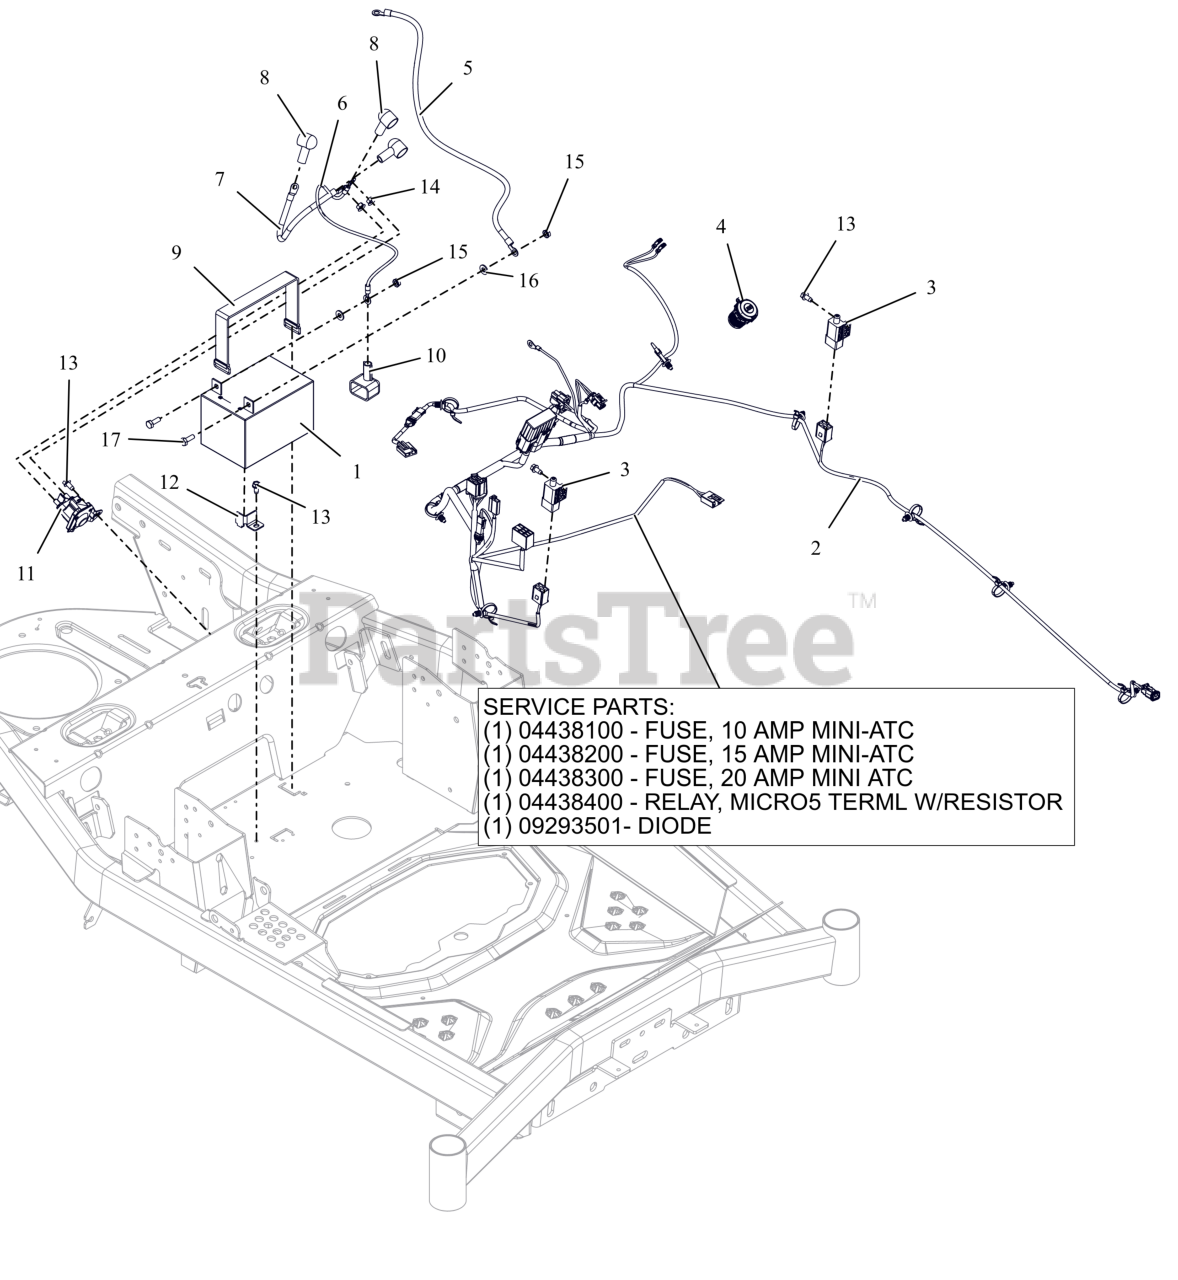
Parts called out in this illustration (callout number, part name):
1	BATTERY, 12V 12A -190CCA
2	HARNESS, MAIN IKON 23
2	FUSE,10 AMP MINI-ATC
2	FUSE,15 AMP MINI-ATC
2	FUSE,20 AMP MINI ATC
2	RELAY,MICRO5 TERML W/RESISTOR
2	DIODE, CONNECTOR SHELL
3	SWITCH-BRAKE NO/NO-POST & HOLE
4	USB, DUAL PORT USB-C, 12V BLK
5	CABLE-NEGATIVE BATTERY 24.00"
6	CABLE,POS W/2 1/4 RING 18.5 LG
7	CABLE, POS W/(2)1/4 RING 9.0LG
8	BOOT, EYELET TERMINAL
9	STRAP- RUBBER
10	INSULATOR
11	SOLENOID, STARTER (SEALED)
12	RETAINER, BATTERY CORNER (BLACK)
13	SCR-TAP .25-20X.50 HWH ZCC
14	NUT- M6-1.0 W/ CONICAL WASHER
15	NUT-KEPS .250-20 ZCC
16	WSHR,FLT .281X.625X.065 ZCC
17	BLT, HEX .25-20X.75 G5 ZCC
